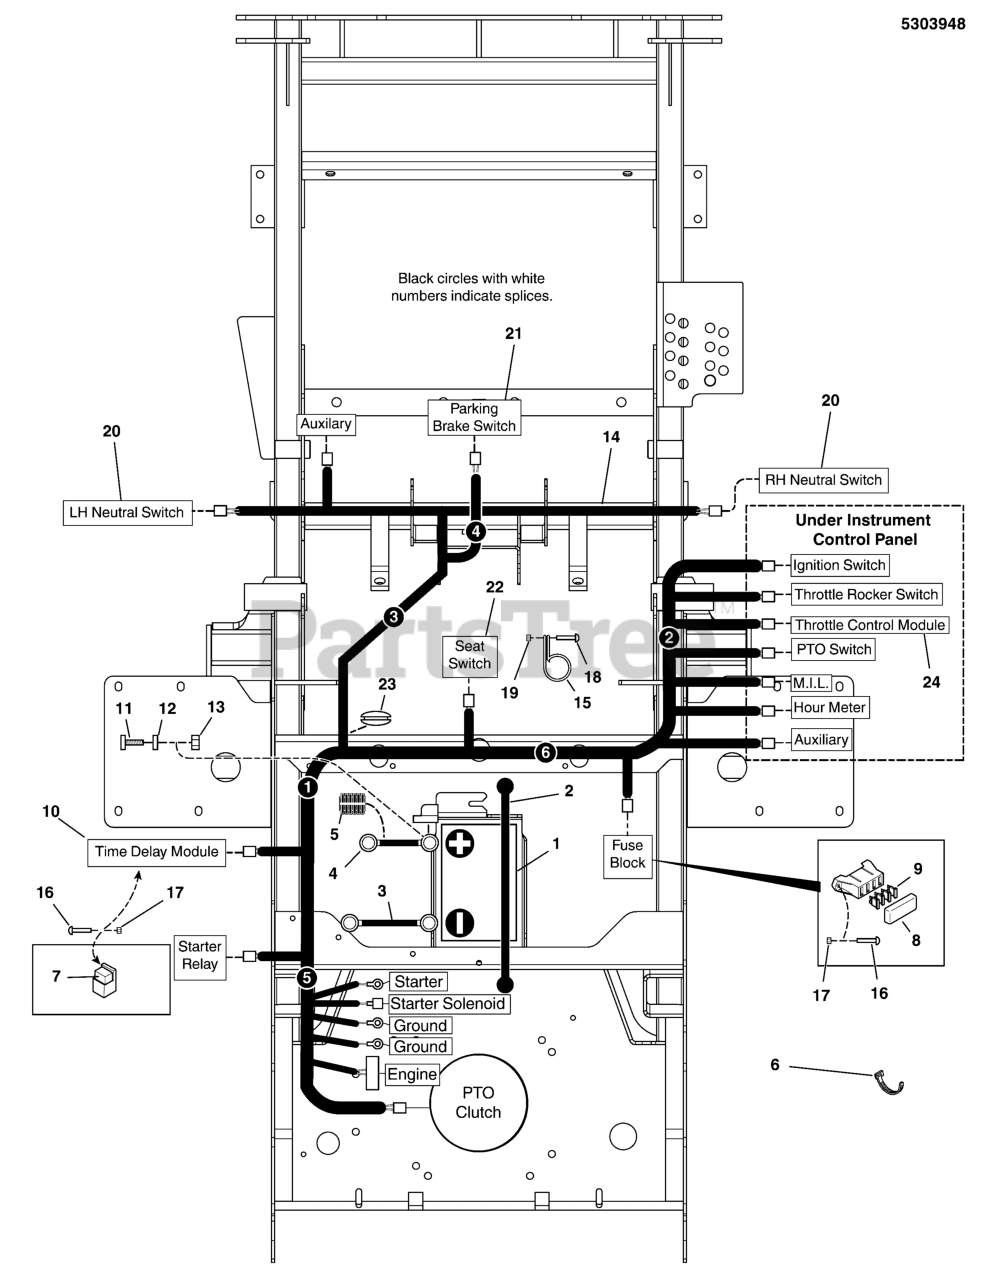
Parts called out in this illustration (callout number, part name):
1	BATTERY, WET ( BCIU1, 350 CCA)
2	STRAP-BLACK RUBB
3	BATTERY CABLE, NEG, 22, 1/4-5/16
4	BATTERY CABLE, POS, 22, 1/4-5/16
5	WIRE LOOM, 3/8 ID X 16 IN
6	TIE, SELF-LOCKING, 12"
7	RELAY, 12V, 40A
8	COVER, VINYL FUSEBLOCK
9	FUSE, ATO, 20 AMP
9	FUSE, ATO-15 (15 AMP)
10	MODULE, TIME DELAY
11	BOLT, 1/4-20 X 3/4 GD5 CZ
12	WASHER, 1/4 SAE
13	NUT, 1/4-20 HEX NYLOCK FLANGE
14	WIRE HARNESS, KAWI DFI, IS3200
15	CLAMP, VINYL INSULATED
16	SCREW, #10-24 X 3/4 ROUND PHILLIPS
17	NUT, #10-24 HEX NYLON LOCK
18	SCREW,1/4-20X1,ZINC PHOS & OIL
19	NUT, 1/4-20 HEX SERR. FLANGE
20	SWITCH, PLUNGER, NO, SINGLE POLE SNAP-IN
21	SWITCH, LOW PROF, NC/NO
22	SWITCH, PLUNGER, N.C.
23	GROMMET, 1-1/2" ID FOR 1/4" METAL
24	MODULE, THROTTLE CONTROL, KAV DFI
